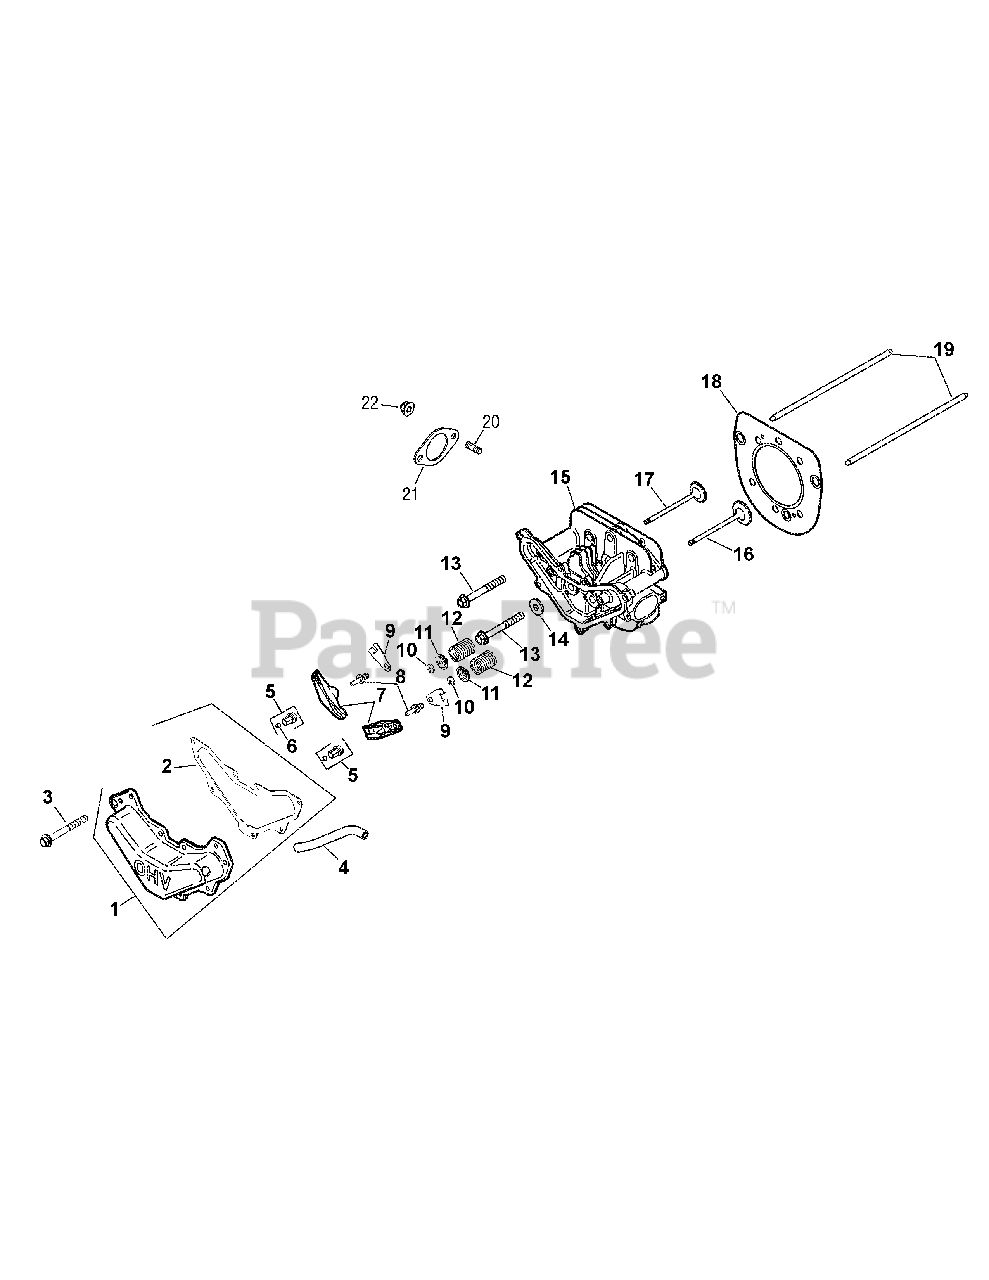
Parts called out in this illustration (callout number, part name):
1	Kit, Valve Cover
2	Gasket, Valve Cover
3	Screw, Hex. Flange M6x1.0x20
4	Hose, Breather
5	Pivot, Rocker Arm
8	Stud, Rocker
9	Plate, Push Rod Guide
10	Lock, Retainer
11	Cap, Valve Spring
12	Spring, Valve
13	Screw, Hex. Flange M10x1.5x37
14	Washer, Flat 1/2"
15	Head, Cylinder
16	Valve, Exhaust
17	Valve, Intake
18	Kit, Head Gasket,
19	Rod, Push
20	Stud, Exhaust
22	Nut, Hex Flange M8x1.25
